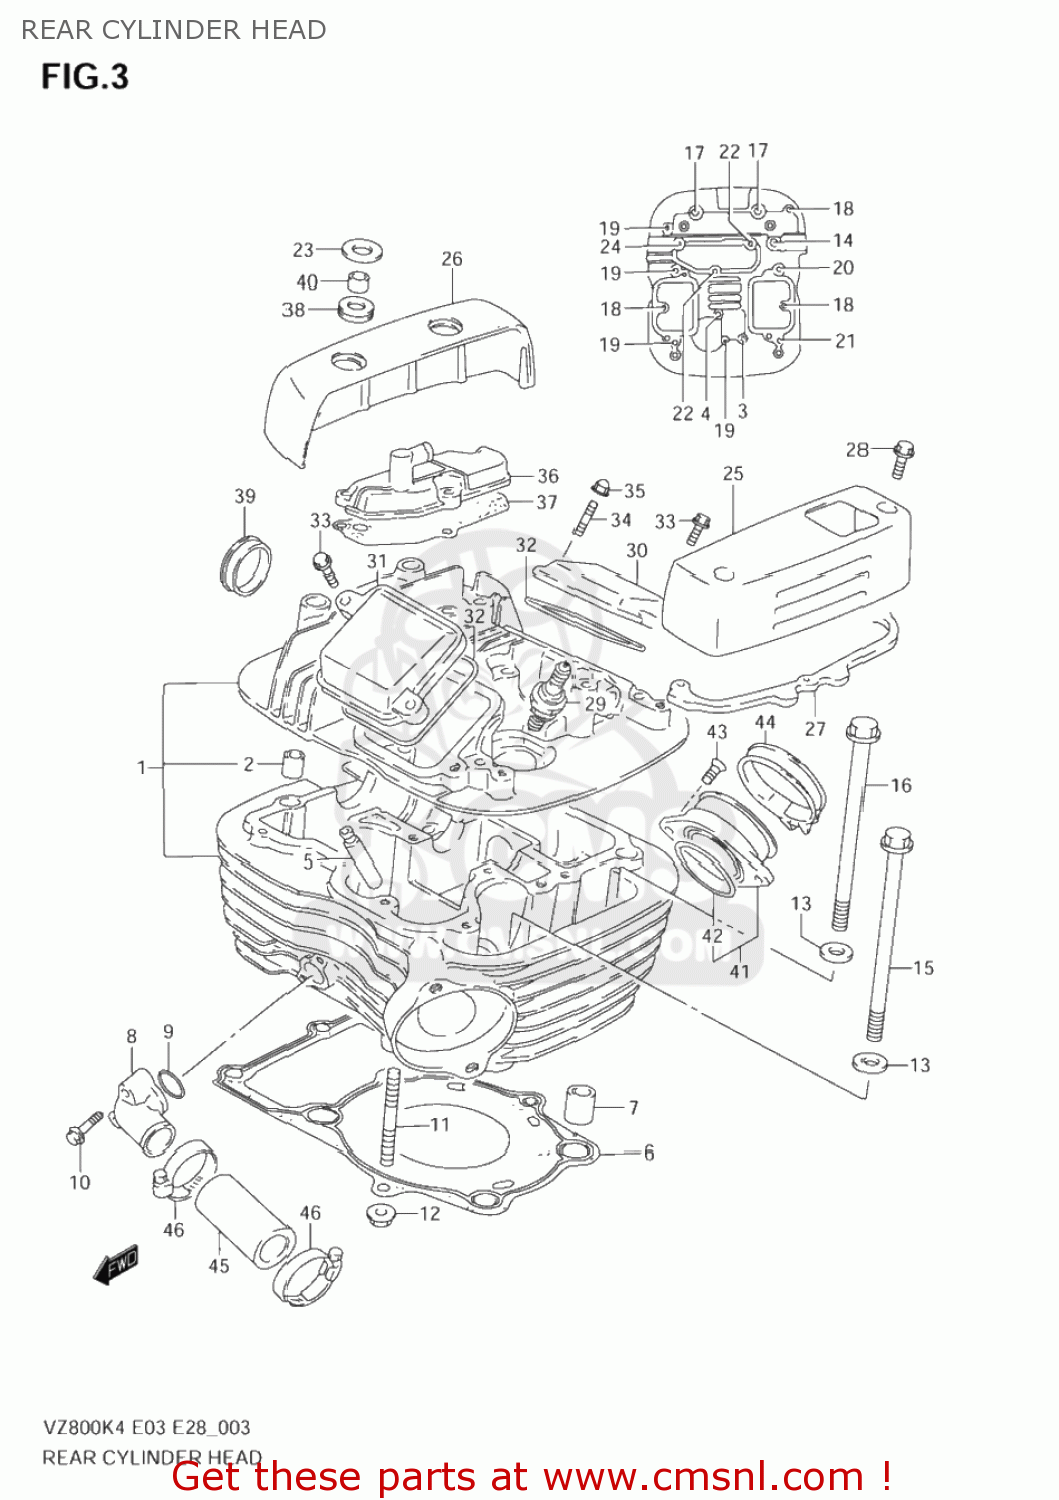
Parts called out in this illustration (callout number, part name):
1	HEAD ASSY,CYLINDER RR
2	PIN(8.4X11X14)
3	BOLT(6X50)
4	BOLT(6X55)
5	GUIDE,VALVE
6	GASKET,CYLINDER HEAD RR (NAS)
7	PIN
8	UNION,CYLINDER HEAD WATER
9	O RING(D:2.4,ID:17.8)
10	SCREW
11	BOLT,STUD
12	NUT
13	WASHER(10.5X22X2.3)
14	BOLT(8X140)
15	BOLT(10X155)
16	BOLT(10X165)
17	BOLT(8X245)
18	BOLT
19	BOLT
20	BOLT
21	BOLT
22	BOLT(6X55)
23	WASHER(8.5X24X1.6)
24	BOLT
25	CAP,CYLINDER HEAD COVER,R-L
26	CAP,CYL HEAD COVER,FL & RR
27	CUSHION,RR,L CAP
28	BOLT(6X35)
29	SPARK PLUG X22E
30	CAP,INSPECTION INTAKE
31	CAP,INSPECTION EXHAUST
32	GASKET,INSPECTION CAP (NAS)
33	SCREW
34	BOLT,STUD
35	NUT
36	COVER,BREATHER
37	GASKET,BREATHER COVER (NAS)
38	CUSHION
39	PLUG(OD:30)
40	BUSH
41	PIPE ASSY,INTAKE RR
42	O RING(D:2.4,ID:39.7)
43	BOLT
44	CLAMP
45	HOSE,CYLINDER HEAD JOINT
46	CLAMP
